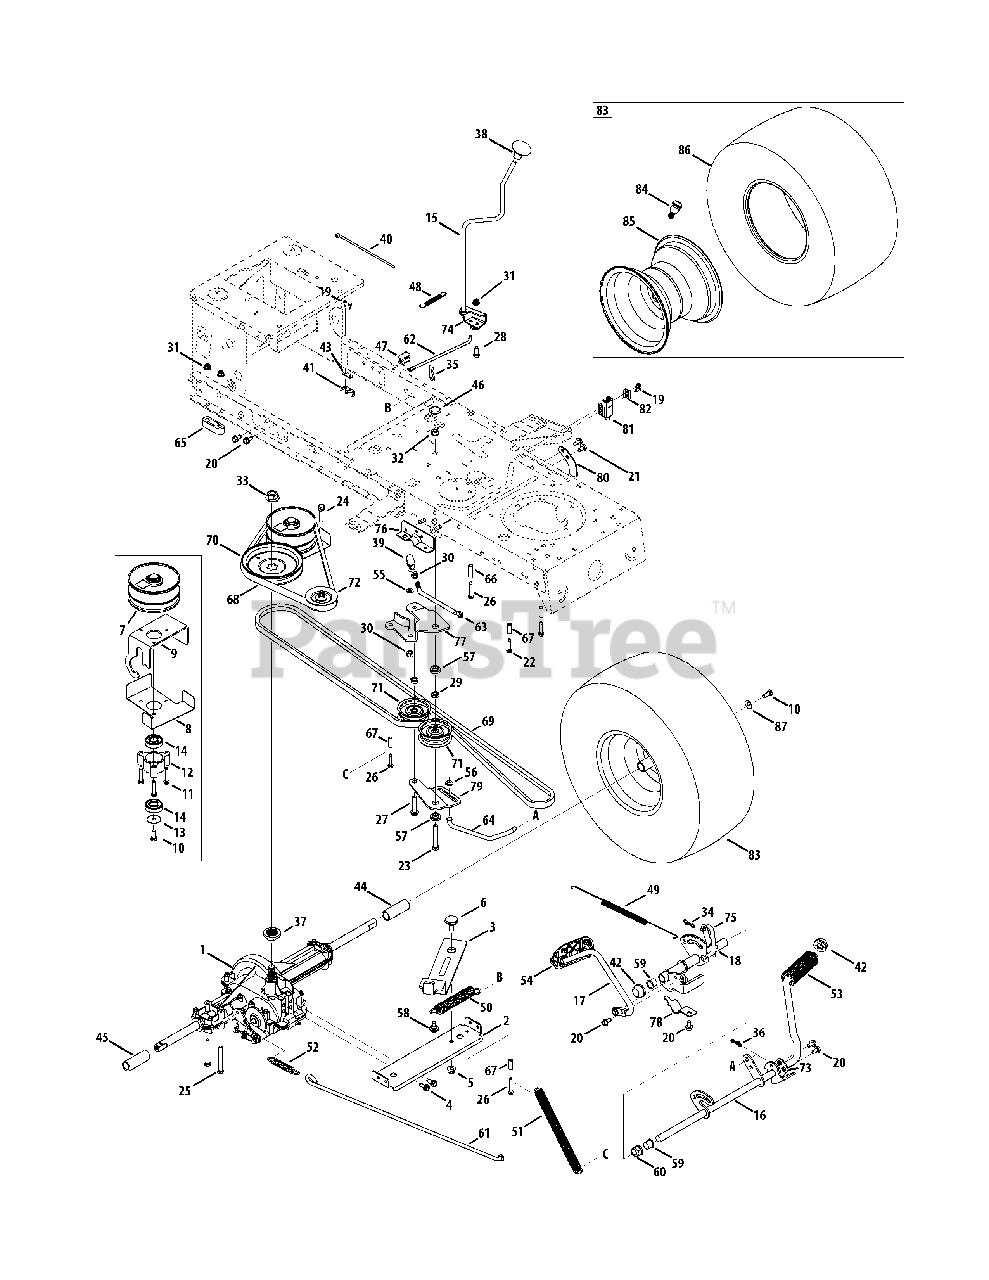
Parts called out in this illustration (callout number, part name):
1	Dr Assembly, Autodrive Lt-5
2	Auto-drive Bracket Assembly
3	Idler Bracket Assembly
4	Tap Screw, 5/16-18 x 0.750
5	Flange Lock Nut, 3/8-16
6	Shoulder Screw, .625 x .217
7	Pulley Assembly, Var. Spd. 4.75 Od
8	Belt Keeper Assembly
9	Variable Bracket Assembly
10	Hex Screw 5/16-24 .750
11	Tap Screw, 1/4-20 1.500
12	Bearing Cup
13	Wash, Flat .330 X 1.25 X .06
14	Ball Bearing, 17 x 40 x 12.6203
15	Lvr Assembly, Shft
16	Pedal Assembly, Drive, Autodrive
17	Pedal Assembly, Cont, Autodrive
18	Bracket Assembly, Pedal, Autodrive
19	Screw, Ab, #8-18, 0.500
20	Screw, Tt, 5/16-18, .750
21	Screw, Tt, 5/16-18, 0.625
22	Screw, Tt, 1/4-20, 1.250
23	Hex Hd. Screw, 3/8-16, 2.50
24	Screw, Ttsems, 3/8-16, 1.500
25	Hex Hd. Screw, 5/16-18, 3.50
26	Screw, Tt, 1/4-20, 1.625,
27	Screw, Tt, 3/8-16 x 1.75
28	Hex Hd. Screw, 5/16-18, .75
29	Nut, Jam, 7/16-20
30	Nut, Hex, 3/8-24
31	Nut, Flange Lock Nut, 5/16-18
32	Nut, Flange Lock Nut, 3/8-16
33	Nut, Flg, 9/16-18
34	Pin, Cot, 3/32, 1.0
35	Pin, Cotter Int- .125 Dia
36	Pin, Cot, Bow-Tie 72
37	Hub, Pulley, 5/8 Spline
38	Knob, Shft
39	Ball, Joint
40	Cable, Tie, 3/16 X .05 X 7.4
41	Switch, Spring, Short
42	Cap, Push 5/8
43	Plate, Insulator Nut
44	Sleeve, .758 X .821 X 3.3125
45	Sleeve, .758 X .821 X 2.4375
46	Plug, Deck Hole, 7/8
47	Shift Plate Bearing
48	Spring, Ext, .38 Od X 3.25 Lg
49	Spring, Extn, .70 Dia X 12.00 Lg
50	Spring, Extn, .97 Od X 6.18 Lg
51	Spring, Extn, .56 X 12.05 x .068
52	Spring, Extn, .59 Od X 4.00 Lg
53	Pad, Foot, 4.0 Long
54	Pad, Cont
55	Wash, Lock, 3/8, Regular Duty
56	Wash, Flat, .375 X .738 X .063
57	Spacer, Shoulder, 1.00 X .38 X .38
58	Screw, Shoulder, .43x.29, Tt, 5/16-18
59	Bearing, Flg, .630 Idx .695 Od X .60
60	Bearing, Hex Flg, .628 Id, Split
61	Rod, Brake, Lt-5 Trans
62	Rod, Shift, Lt-5 Stretch 46"
63	Rod, Adj, Idlr, 3/8
64	Rod, Trans, Footpedal Bypass
65	Spacer, T-Axle .68
66	Spacer, .260 X .372 X 1.420 Lg
67	Spacer, .260 X .375 X 1.030 Lg
68	Belt, V Typ, 5l X 40.9 Lg Poly
69	Belt, V Typ, 5l, 90.80, Poly
70	Pulley, Idlr, Flat 7.25 Od
71	Pulley, Idlr, Flat 2.75 Od
72	Pulley, Idlr, V-Type X 3.06
73	Bracket, Ped, Support Lt-5
74	Bracket, Shft, Adj
75	Plt, Bracket, Reinforcement
76	Bracket, Ped, Frame Rh
77	Bracket, Idlr, Dbl Autodrive
78	Bracket, Supt, Pedal Stap
79	Bracket, Idlr, Center Dbl
81	Interlock Switch
82	Switch Plate
83	Wheel Assembly, 18 x 9.5 x 8 Sq. Sh.
84	Valve Stem
85	Rim Assembly
87	Bell Washer, .340 x .872 x .060
